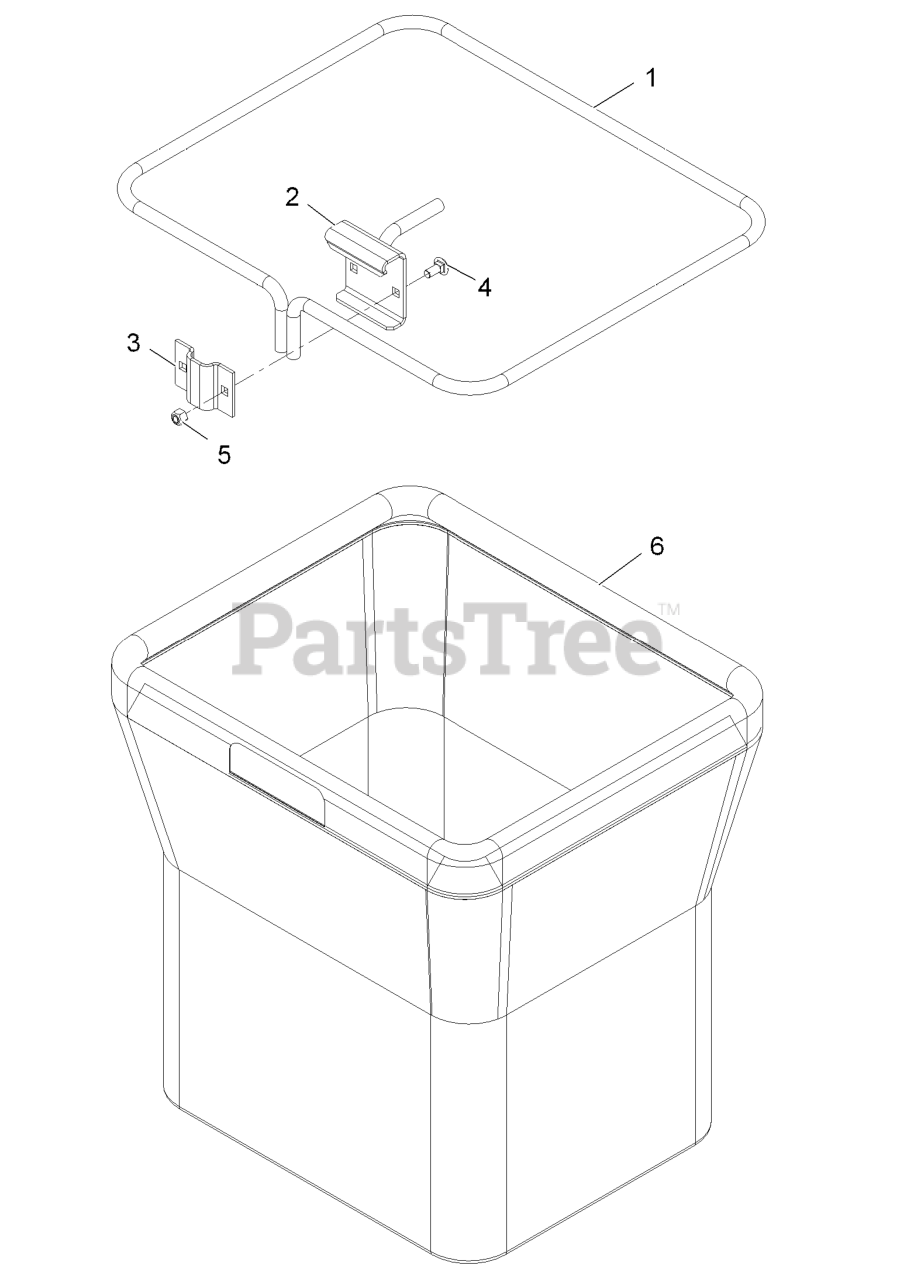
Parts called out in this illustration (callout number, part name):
1	FRAME-BAG
4	BOLT-CARR
5	NUT-LOCK, NI
6	BAG,20 IN. DEPTH
